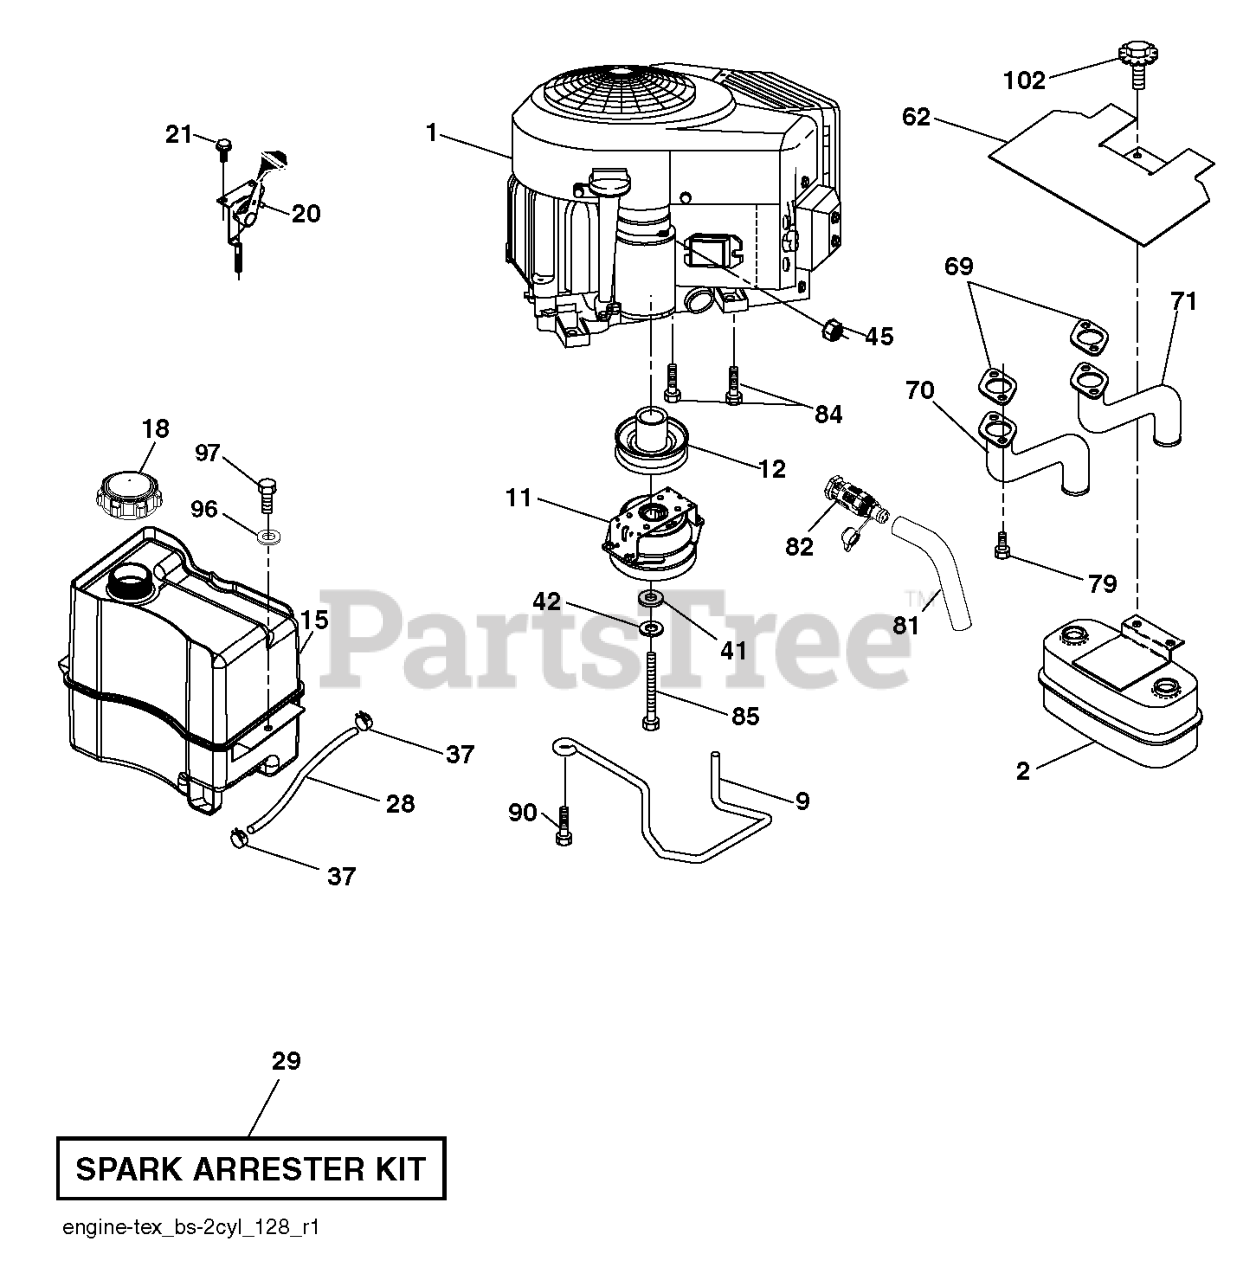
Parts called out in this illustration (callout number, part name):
2	MUFFLER.ASM.TWN.EXTNDED.DFLCTR
9	KEEPER BELT ENGINE
11	CLUTCH.ELECTRIC.LT.48"*
12	PULLEY.ENGINE.TUFFTORQ
15	TANK.ASSEMBL.2.5GAL.NON-EPA
18	CAP ASM.FUEL.2.25"FR.
20	CONTROL.TH/CK.COBRA.B&S.TWN.BK
21	SCREW.#10 X 0.750.BOS
28	LINE.FUEL.20
29	KIT.SPARK ARRESTOR 794945 B&S
37	HOSE CLAMP
42	LOCKWASHER
45	NUT
62	SHIELD.HEAT.MUFFLER
69	GASKET.MUFFLER
70	EXHAUST.TUBE.LH.BS/TWIN
71	EXHAUST.TUBE.RH.B&S.TWIN.INTEK
79	SCREW.SOCKET.HEAD.5/16-18
81	TUBE, DRAIN OIL ASM.
82	VALUE.OIL.DRAIN
84	SCREW.3/8-16
85	BOLT HEX 7/16-20X4-1/4"
87	BOLT 5/1618UNC X 3/4 W/ SEMS
90	SCREW 3/8-16X1
96	WASHER
97	SCREW HEXWSHR 1/4-20X3/4
